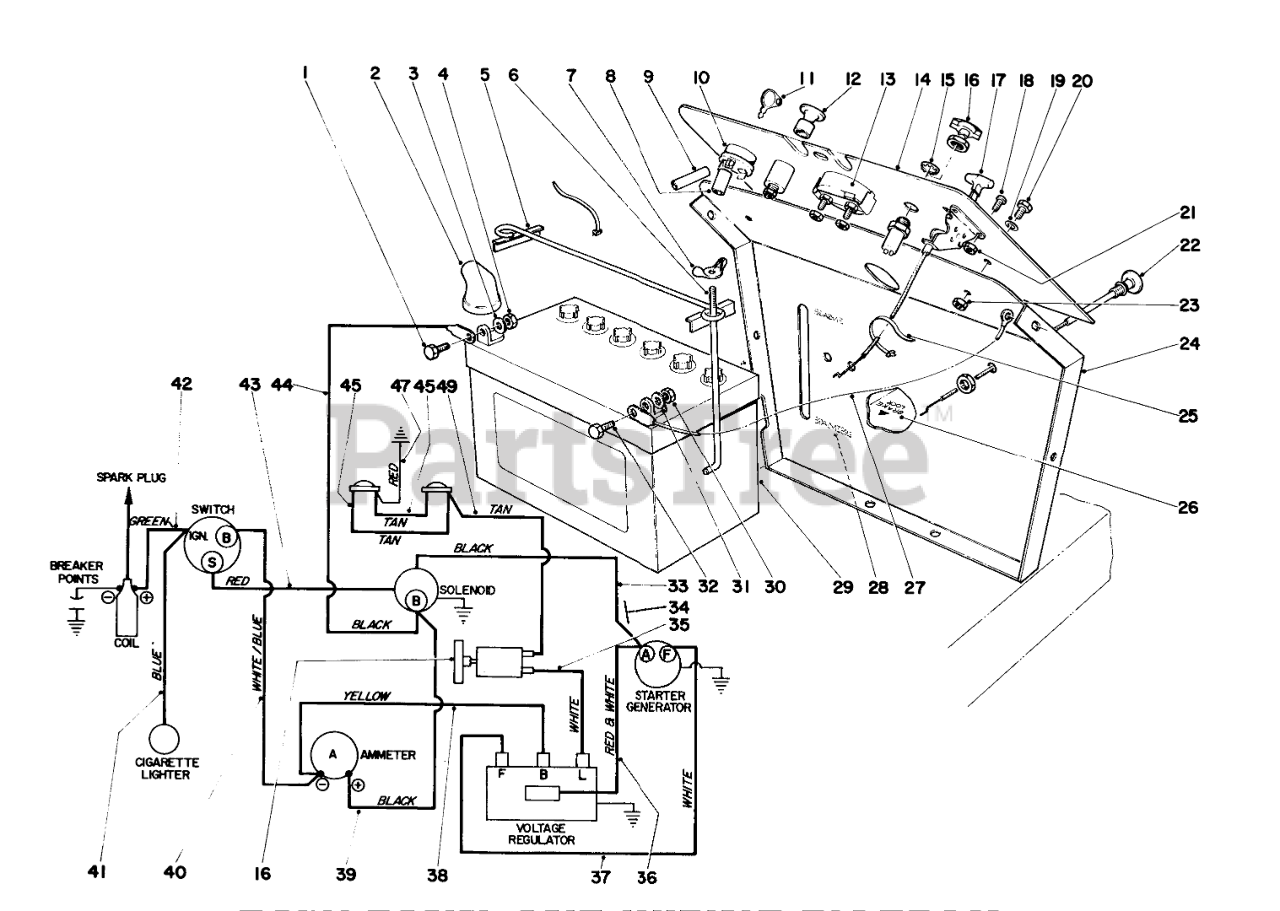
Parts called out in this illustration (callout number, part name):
1	SCREW-HH
2	Battery Boot
3	Washer
4	NUT-HEX
5	Battery Clamp
6	BATTERY BOLT
7	NUT-WING
8	Insulator
9	Insulator
10	Starter Switch
11	Key
12	Cigarette Lighter Assy.
13	Ammeter
14	Dash Panel
15	Plug Button 950
16	Light Switch
17	Throttle Control
18	Machine Screw
19	Washer
20	SCREW-HH
21	NUT-KEPS
22	Choke Control
24	Rear Hood Support
25	Cable Tie
26	Decal Brake
28	Decal Engage & Disengage
29	Battery
30	NUT-HEX
31	Washer
32	SCREW-HH
34	Wiring Harness
35	Blue Wire
45	Wire 960
47	Wire 12 H.P.
49	Wire 960
